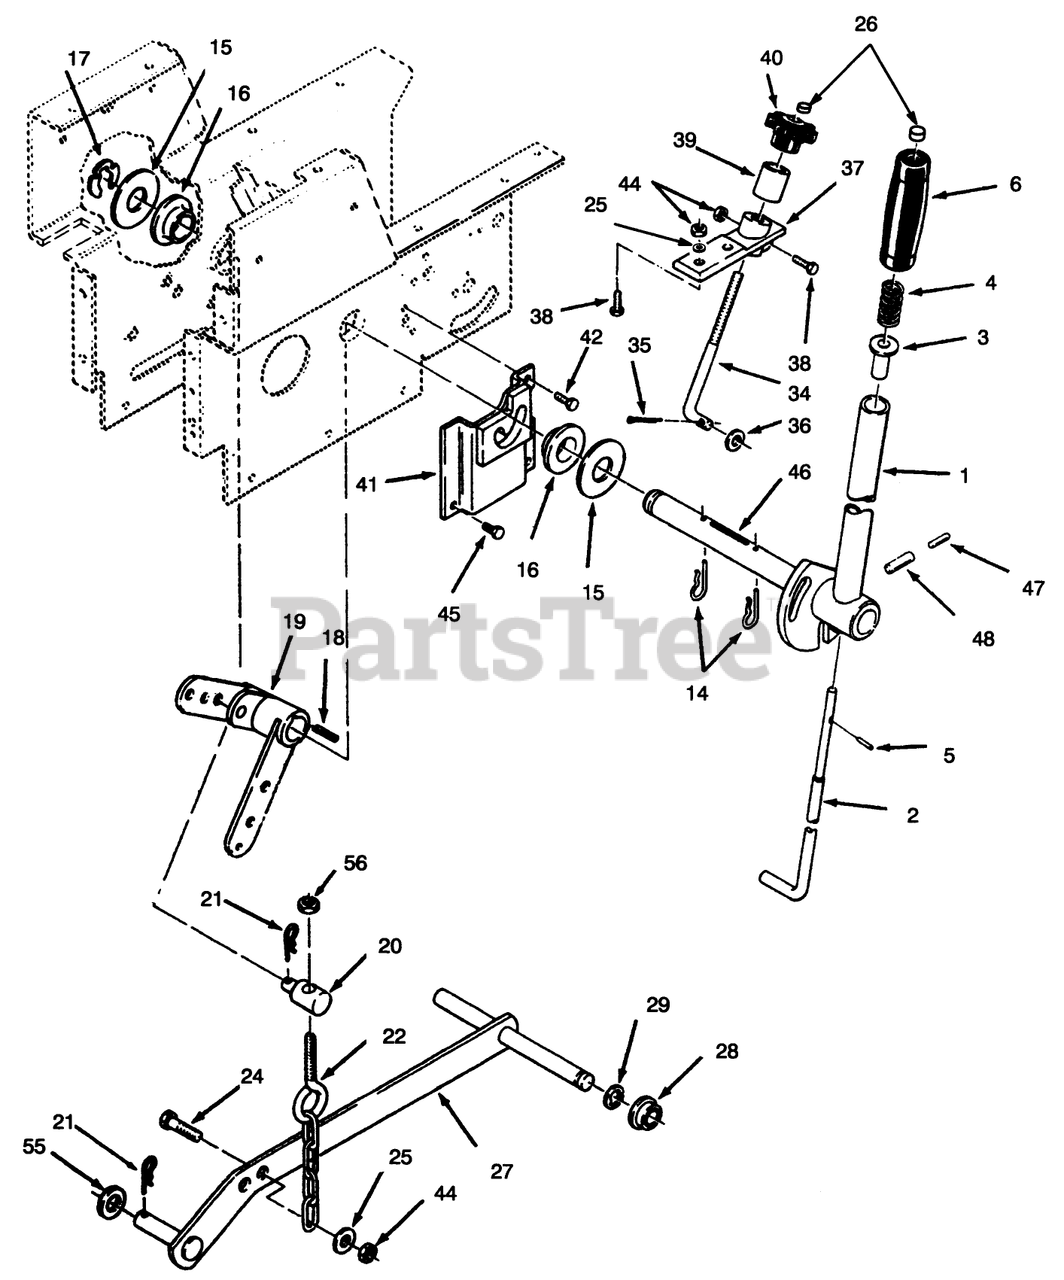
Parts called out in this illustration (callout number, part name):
2	ROD-LATCH LIFT
3	RETAINER-SPRING
4	SPRING-COMPRESSION
5	PIN-SPIROL
6	HANDGRIP
14	PIN-HAIR
15	WASHER-FLAT
16	BEARING-FLANGE
17	RING-RETAINING
18	KEY-SQUARE
19	LIFT LEVER ASM
20	TRUNNION-LIFT
21	PIN-HAIR
22	CHAIN-LIFT
24	SCREW-HH
25	WASHER-PLAIN
26	CAP-ROD, PLUNGER
28	BUSHING
29	RING-RETAINING, EXTERNAL
34	ROD-HEIGHT CONTROL
35	PIN-COTTER
36	WASHER-FLAT
38	SCREW-HH
40	KNOB-LIFT CONTROL
44	NUT-LOCK, NI
46	SHAFT-LIFT LEVER
47	PIN-SPRING
48	PIN-ROLL
55	WASHER-FLAT
56	NUT-LOCK, NI
